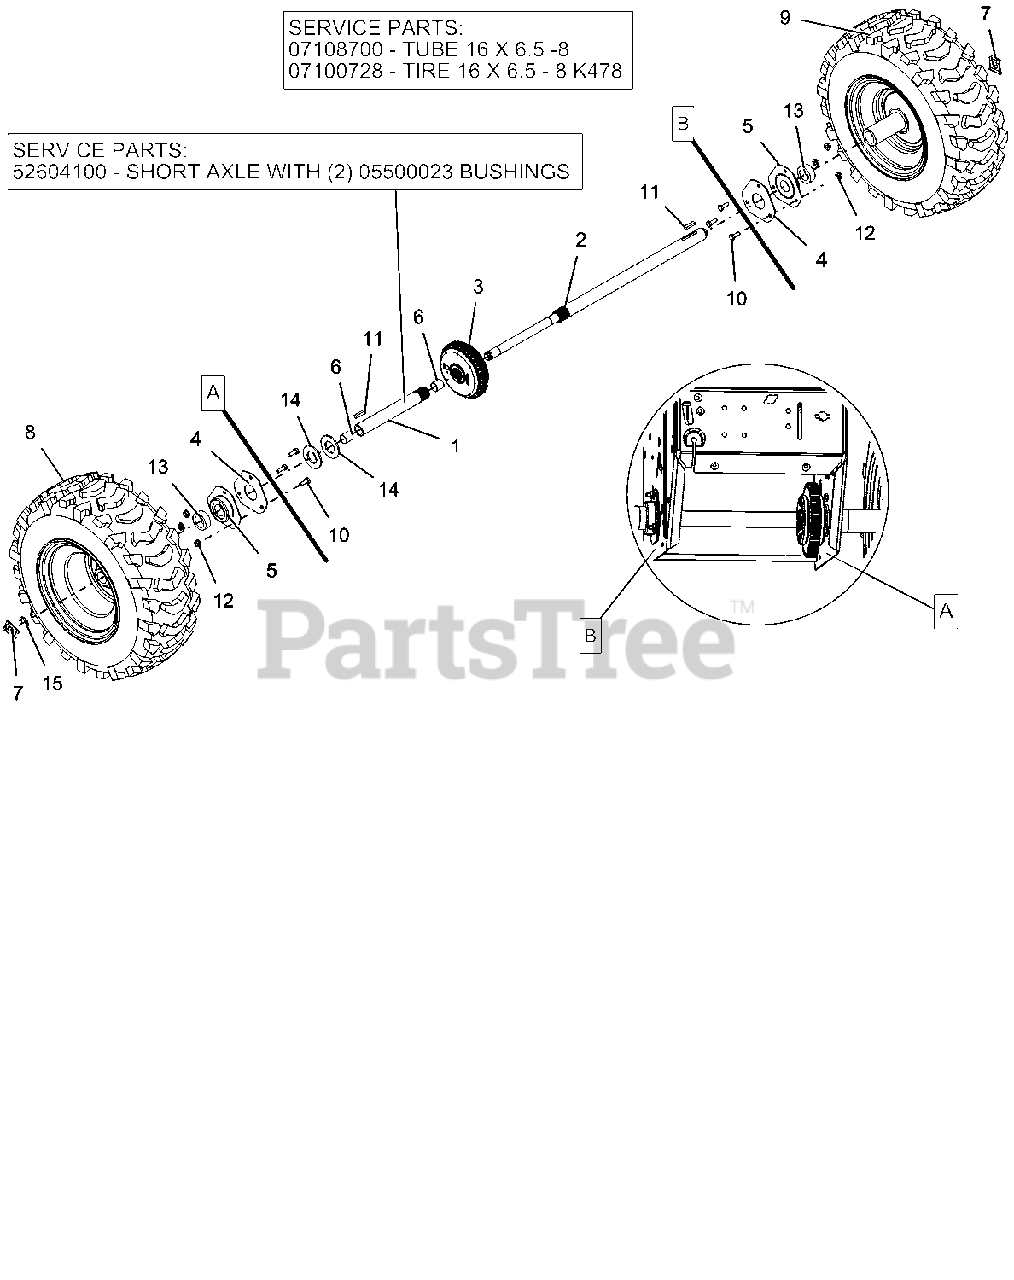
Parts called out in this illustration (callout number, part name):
1	BSHG-SLV .706X.764X.75 BRZ
1	AXLE, SHORT-PRO AUTO DIFF
1	AXLE, SHORT-AUTO W/BUSHINGS
2	AXLE, LONG-PRO AUTO DIFF
3	DIFFERENTIAL, AUTOMATIC
4	PLATE, BEARING SPACER
5	BRG-FLG 1.003/1.000 3 BOLT
6	BSHG-SLV .706X.764X.75 BRZ
7	CLIP, SNAP .625 DIA
8	TIRE/WHEEL, RH 16X6.50-8 DIFF
9	TIRE/WHEEL, LH 16X6.50-8 DIFF
10	@BLT-HEX .25-20X.75 GR5 YWZC
11	KEY-RECT .25X.188X1.00
12	@NUT-LK-CTR-FLG .25-20 YWZC
13	SPACER, PRO AXLE BEARING
14	WSHR-FL-STL- 1.062X2.0X.134 YZ
15	RG-RTNG-EXT .625X.042
16	TUBE
17	TIRE, 16X6.50-8 K478
